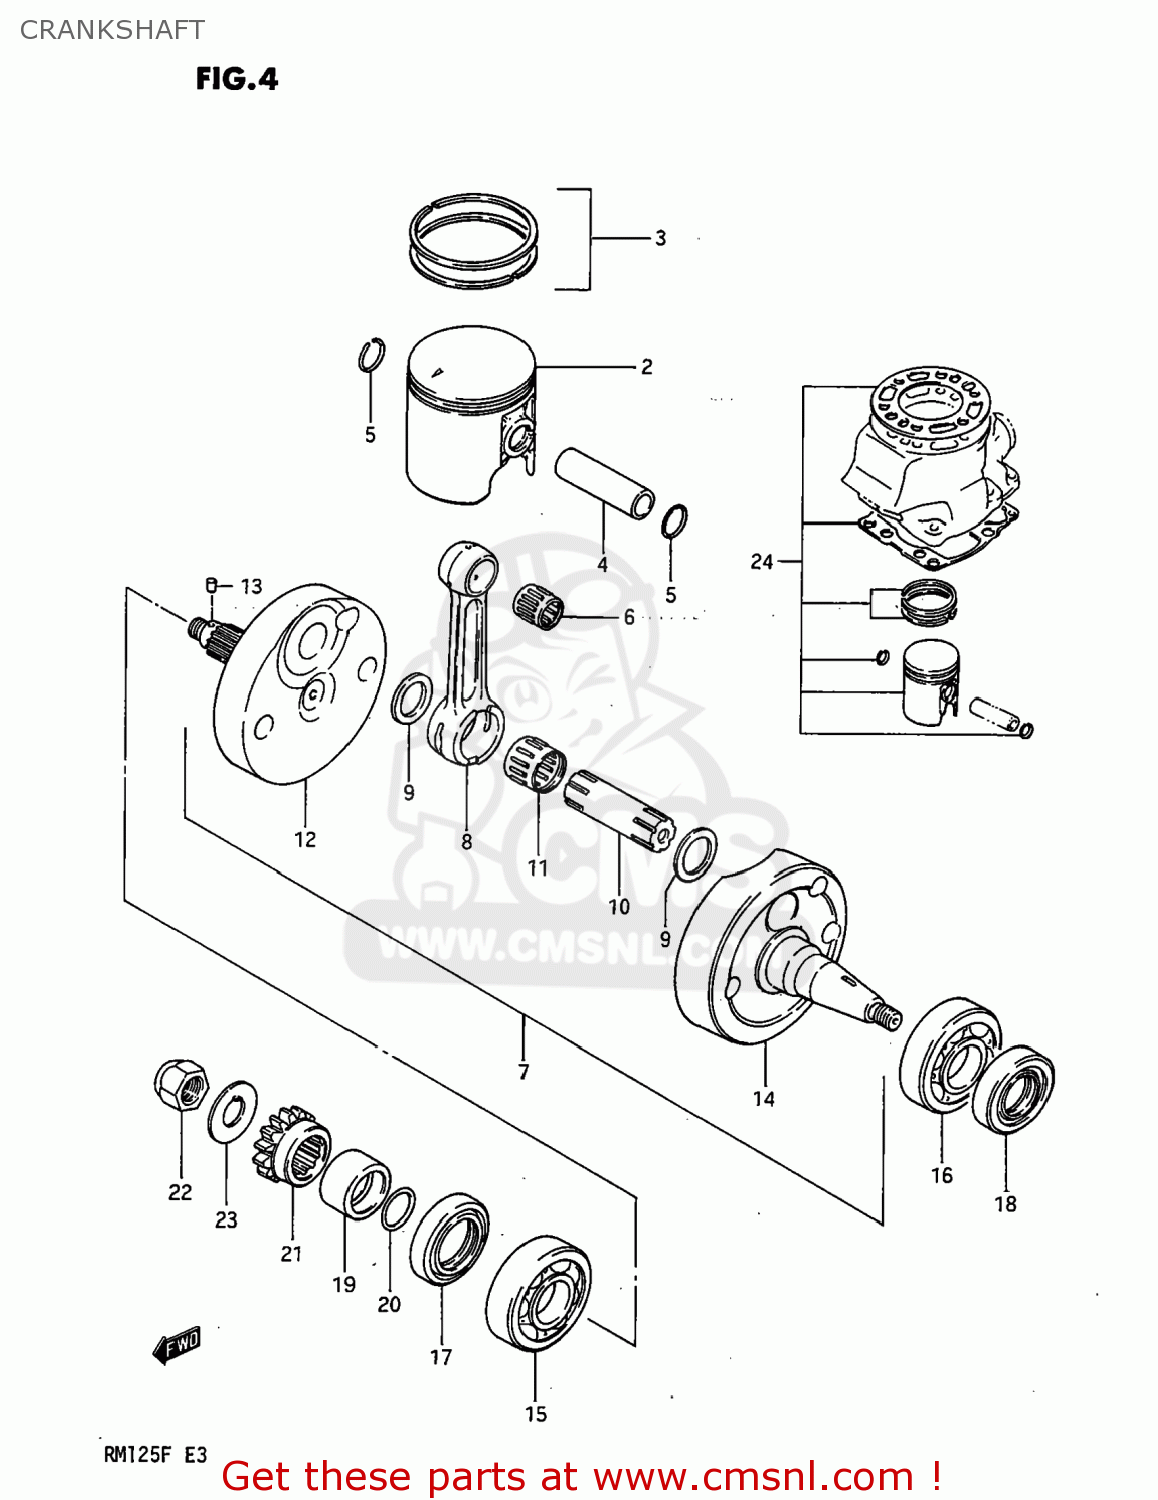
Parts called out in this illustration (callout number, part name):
1	PISTON SET (STD)
2	PISTON
3	RING SET,PISTON
4	PIN,PISTON
5	RING,SNAP 14MM
6	BEARING
7	CRANKSHAFT ASSEMBLY
8	CONNECTING ROD
9	WASHER(22X35X1)
10	PIN,CRANK
11	BEARING
12	CRANKSHAFT
13	PIN 3X5
14	CRANKSHAFT,LEFT
15	BEARING
16	BEARING
17	SEAL,OIL(28X40X8)
18	SEAL,OIL(18X30X8)
19	SPACER,PRIMARY DRIVE GEAR
20	O RING(D:2.4,ID:19.8)
21	GEAR,PRIMARY DRIVE
22	NUT
23	WASHER
24	PISTON SET
